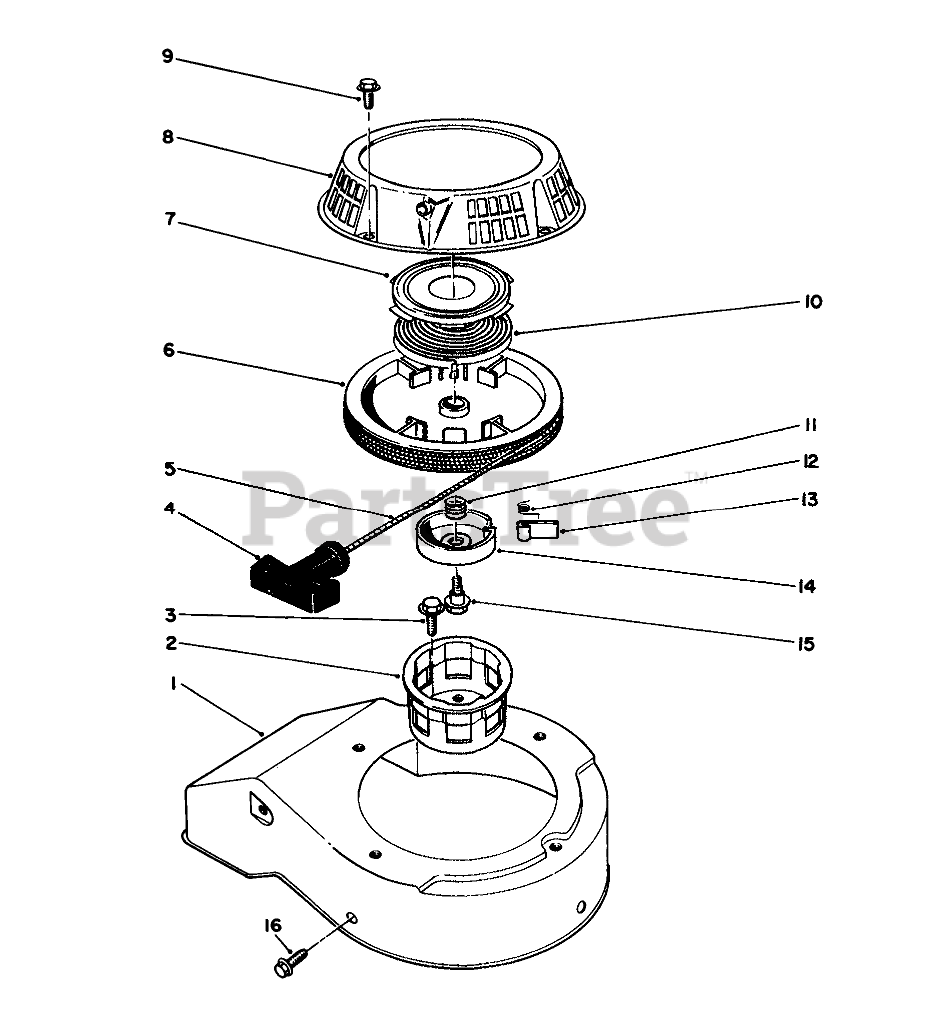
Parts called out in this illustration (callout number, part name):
1	Cover-Cooling Fan
2	PULLEY-CUP, STARTER
4	HANDLE-RECOIL
5	ROPE-STARTER
7	Retainer-Spring, Recoil
8	CASE-STARTER
9	SCREW-HHF
10	Spring-Recoil
11	SPRING
12	SPRING
14	RETAINER
17	Insert Handle
